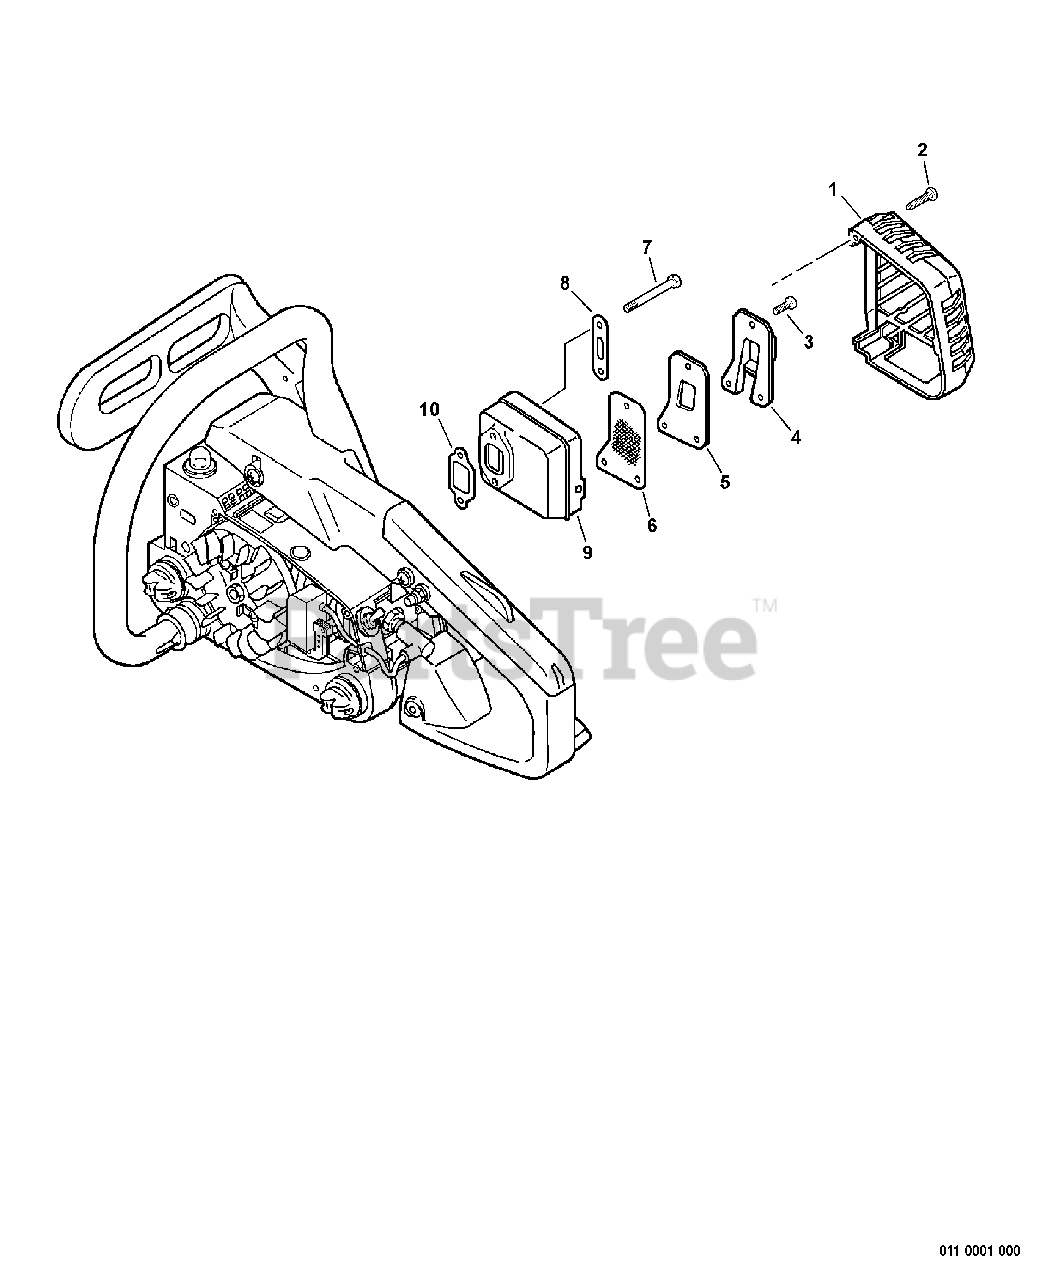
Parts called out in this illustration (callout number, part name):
1	COVER, EXHAUST
2	SCREW - 5X20 -- TAPPING
3	SCREW - 4X12
4	GUIDE, EXHAUST
5	GASKET, EXHAUST
6	SCREEN, SPARK ARRESTOR
7	SCREW - 5X45
9	MUFFLER
10	GASKET, EXHAUST
